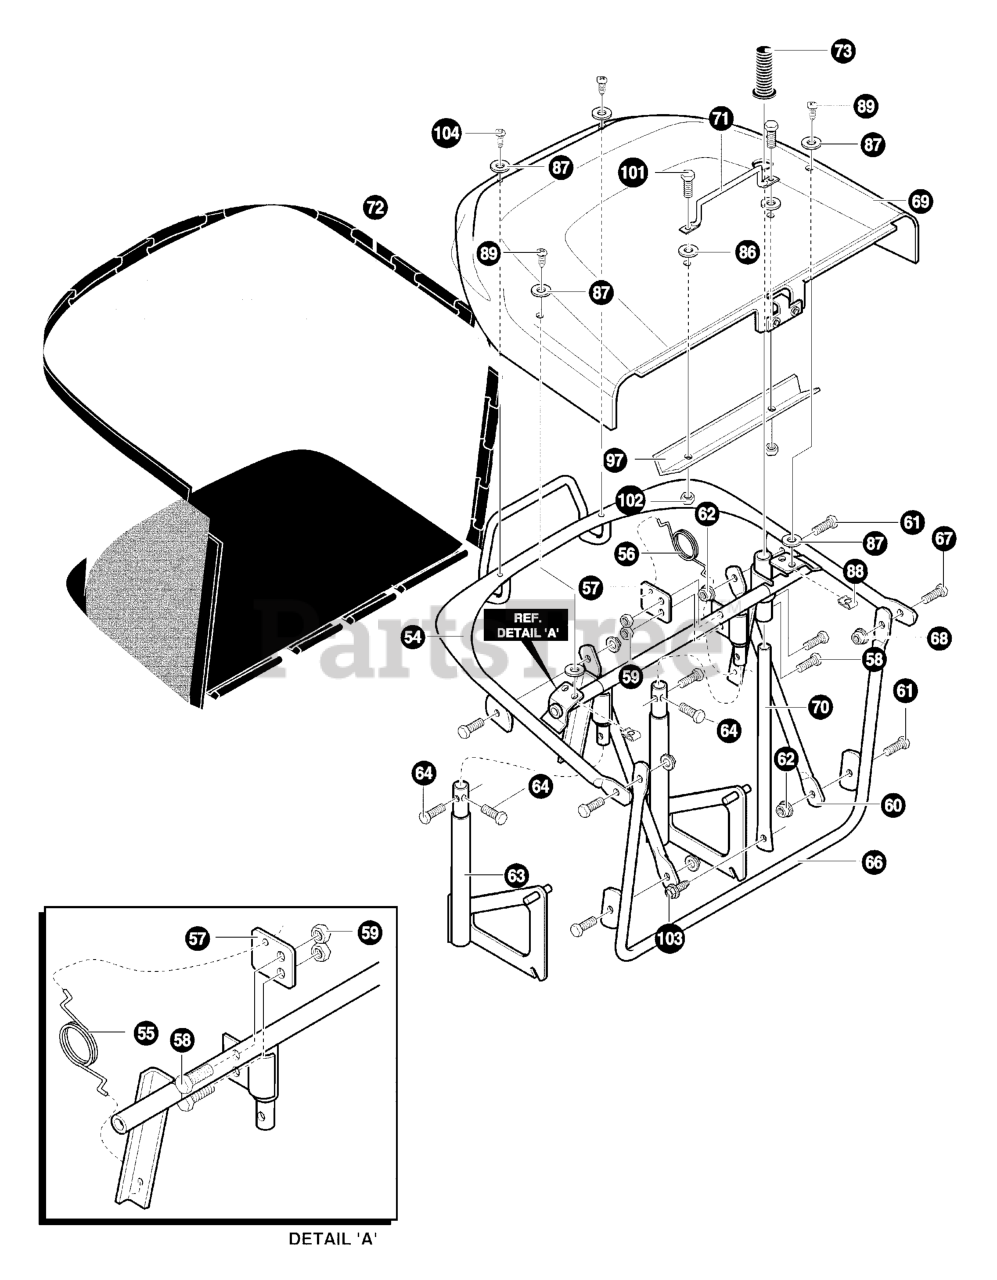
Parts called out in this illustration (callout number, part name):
54	ASM. WLD- UPPER FRAME
55	SPRING, TORSION RH BAG CLOSE
56	SPRING, TORSION LH BAG CLOSE
57	BRACKET, SPRING COLLECTOR
58	SCREW, 1/4-20X.62
59	NUT, 1/4-20
60	BRACE, FRAME COLLECTOR
61	SCREW, 1/4-20X.62
62	NUT, 1/4-20
63	ASM. SUPPORT COLLECTOR
64	SCREW, 5/16-18 x 1.50
66	ASM., FRONT FRAME COLLECT
67	SCREW, 1/4-20X.62
68	NUT, 1/4-20
69	TOP COLLECTOR ASM.
70	HANDLE, DUMP REBA COLLECTOR
71	HANDLE, REBA COLLECTOR
72	REBA COLLECTOR BAG
73	RUBBER GRIP
85	NUT, 5/16-18
86	WASHER, .281X1.25X.06
87	WASHER, FLAT
88	NUT, 1/4-20 TINN U
89	SCREW, 1/4-20X.63
97	BRACE, BAGGER
101	SCREW, 1/4-20X1.50
102	NUT, 1/4-20
103	SCREW, #12X.50
104	SCREW, #12X.50
